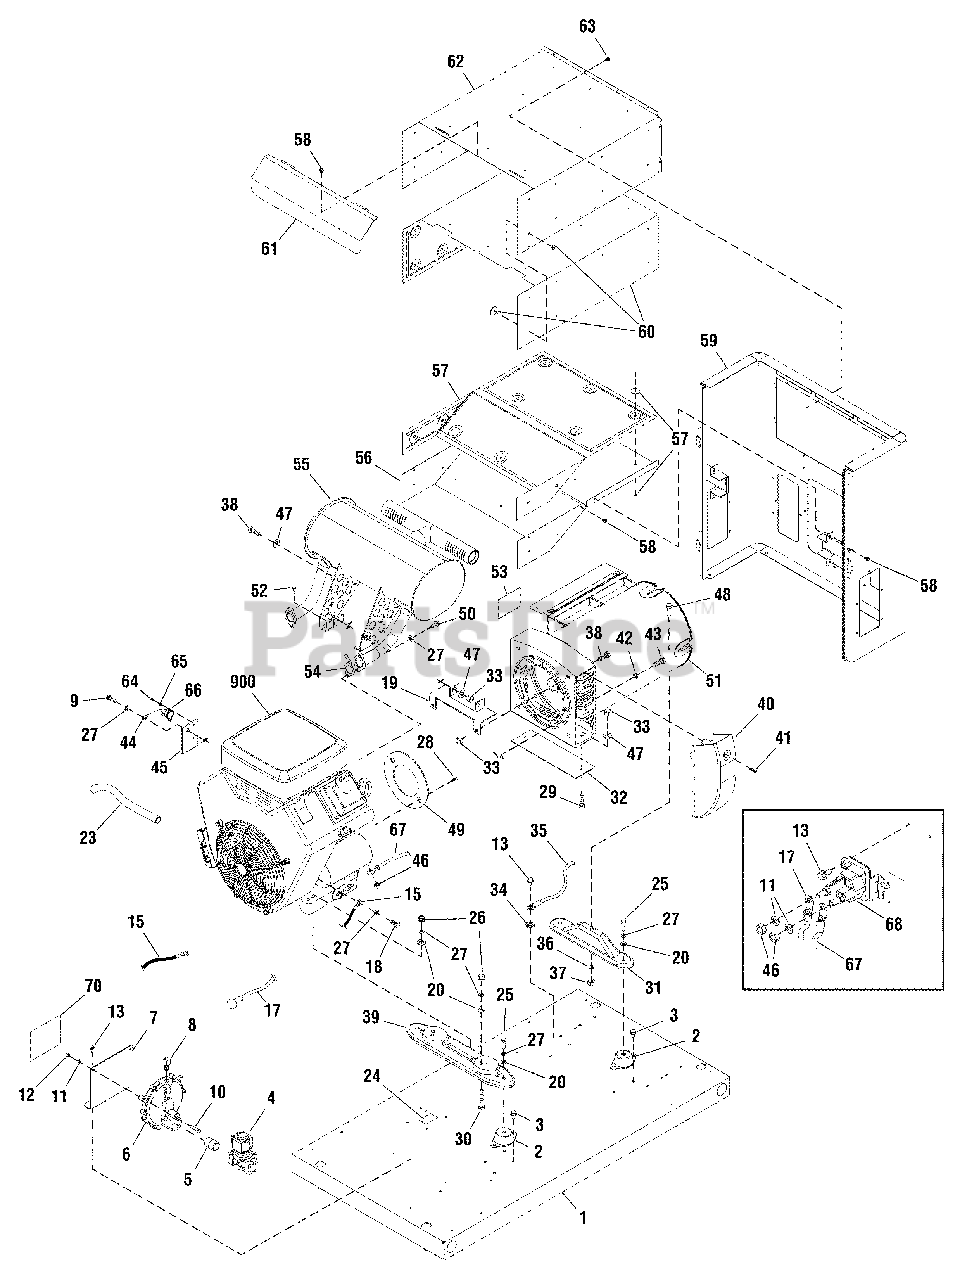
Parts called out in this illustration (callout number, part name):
2	MOUNT, Vibration
4	SOLENOID, Gas Fuel
6	REGULATOR, NG/LPG
9	* CAPSCREW, Hex Head, M8-1.25 x 12
10	* CAPSCREW, Hex Head, M6-1.0 x 30
11	* WASHER, Lock, 1/4
12	* NUT, M6-1.0
13	BOLT
15	CABLE, Battery, Black
17	CABLE, Battery, Red
18	* CAPSCREW, M8-1.25 x 16
20	* WASHER, Flat, 5/16-M8
23	HOSE, Oil Drain
24	DECAL, Oil Drain
25	* CAPSCREW, Hex Head, 5/16-18 x 1
26	* NUT, 5/16-18
27	* WASHER, Lock, 5/16-M8
28	* CAPSCREW, Hex Head, 5/16-24 x 3/4
29	* CAPSCREW, Hex Head, 1/4-20 x 1
30	* CAPSCREW, Hex Head, 5/16-18 x 1-3/4
31	SUPPORT, Alternator
34	* WASHER, Shakeproof, M6-1/4
36	* WASHER, Lock, M10
37	* NUT, Hex, M10
38	* CAPSCREW, Hex Head, 1/4-20 x 3/4
39	SUPPORT, Alternator
42	* WASHER, Lock, 3/8
43	* CAPSCREW, Hex Head, 3/8-16 x 1-1/4
45	PLATE, Temp Switch
46	* NUT, Hex, 14-20
47	* WASHER, Flat, M6
48	* CAPSCREW, Hex Head, M10-1.5 x 30
51	ALTERNATOR
53	DECAL
59	BULKHEAD, Alternator
62	BOX, Muffler Top
64	* SCREW, Phillips Head, 4-40 x 0.19
65	* WASHER, Lock, #4
66	SWITCH, Temp
68	SOLENOID, Starter
900	** ENGINE
